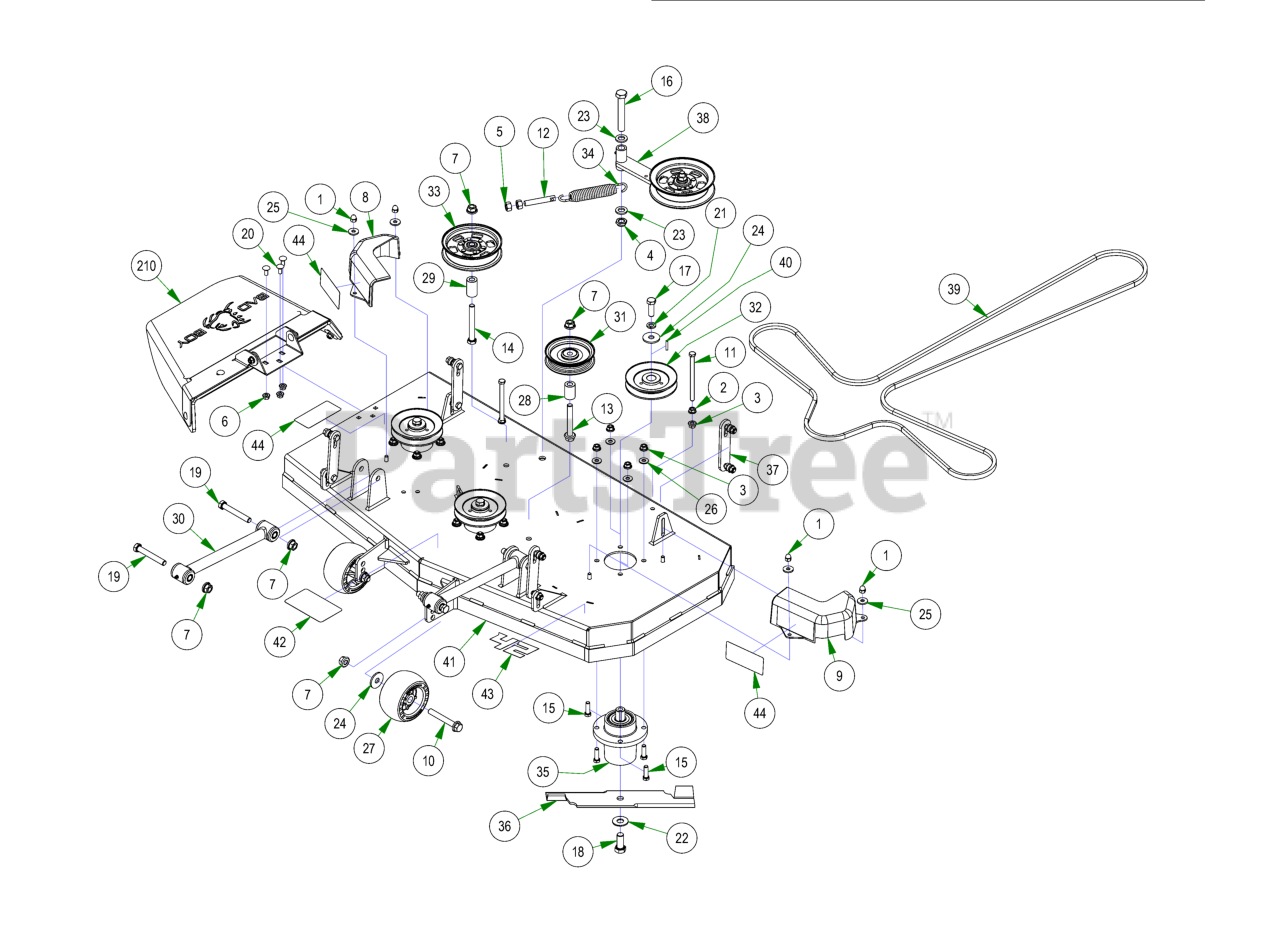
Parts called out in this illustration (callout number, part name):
1	5/16-18 ACORN NUT HIGH-CROWN ZC
2	3/8-16 HEX SERRATED FLANGE NUT HARD/ZINC
3	3/8-16 NYLON INSERT FLANGE LOCKNUT (GR.F) ZINC
4	5/8-11 NYLON INSERT JAM LOCKNUT ZINC
5	1/2-13 HEX NUT ZINC
6	5/16-18 NYLON INSERT FLANGE LOCKNUT ZINC
7	1/2-13 NYLON INSERT FLANGE LOCKNUT ZINC
8	pulley cover chute side
9	pulley cover non-chute side
10	1/2-13 X 90MM HEX FLANGE BOLT W/SHOULDER (GR.8) ZINC
11	3/8-16 X 5-1/4 HEX CAP SCREW (GR.5) ZINC
12	All Thread
13	1/2-13 X 3-1/2 HEX FLANGE BOLT (GR.8) ZINC
14	1/2-13 X 4 HEX CAP SCREW (GR.8) ZINC YELLOW
15	3/8-16 X 1-1/4 HEX CAP SCREW (GR.5) ZINC
16	5/8-11 X 4 HEX CAP SCREW (GR.8) ZINC YELLOW
17	1/2-20 X 1-1/2 HEX CAP SCREW (GR.5) ZINC
18	5/8-18 X 1-1/2 HEX CAP SCREW (GR.8) ZINC YELLOW
19	1/2-13 X 3-1/2 HEX CAP SCREW (GR.5) ZINC
20	5/16-18 x 3/4 Carriage Bolt
21	1/2 SPLIT LOCKWASHER (GR.8) ZINC/YELLOW
22	5/8 USS FLAT WASHER (1-3/4" OD) GR.8 ZINC YELLOW
23	.635 ID X 1.120 OD X .140 THICK FLAT WASHER NYLON
24	1/2 BELLEVILLE WASHER (1-5/8 OD X .140 THK) ZINC
25	.360 ID X .983 OD X .120 THICK FLAT WASHER NYLON BLACK
26	5/16 USS FLAT WASHER (7/8 OD) ZINC
27	Deck Wheel
28	.502 ID X .750 OD X 1.500 Long Spacer
29	1 3/4" Pulley Spacer
30	Hybrid Turnbuckle/Deck Locator
31	4 3/4" Idler Pulley
32	42" MZ Spindle Pulley
33	5-3/4 Idler Pulley
34	Deck Idler Spring
35	Spindle Assembly-MZ
36	42" High Lift Fusion Blade-MZ
37	Deck Hanger Assembly
38	2017 MZ/ZT Deck Idler Assembly
39	2023 42" Deck Belt
40	3/16 X 1 SQ MACHINERY KEY 1018 STL ZINC
41	2023 42" x 4" Deck
42	2017 MZ Magnum 48"/42" Deck Route Decal
43	42" Deck Decal
44	Danger Decal-Spindle/Discharge
